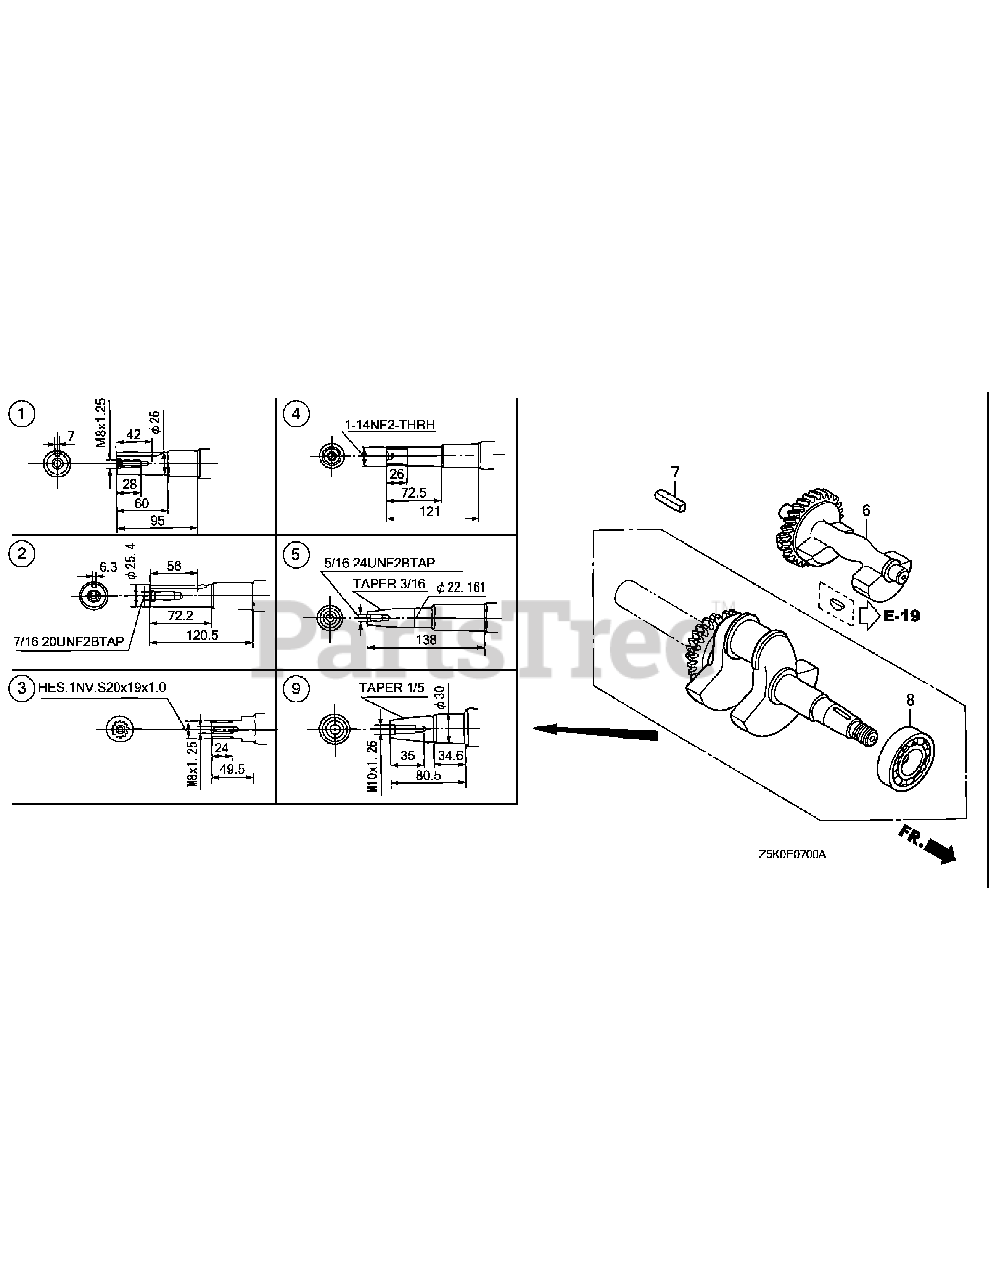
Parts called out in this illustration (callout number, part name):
2	Crankshaft Comp.
6	Weight, Balancer
7	Key, 6.3X6.3X43
8	Bearing, Radial Ball(6206 Sh)
9	Crankshaft Comp.
